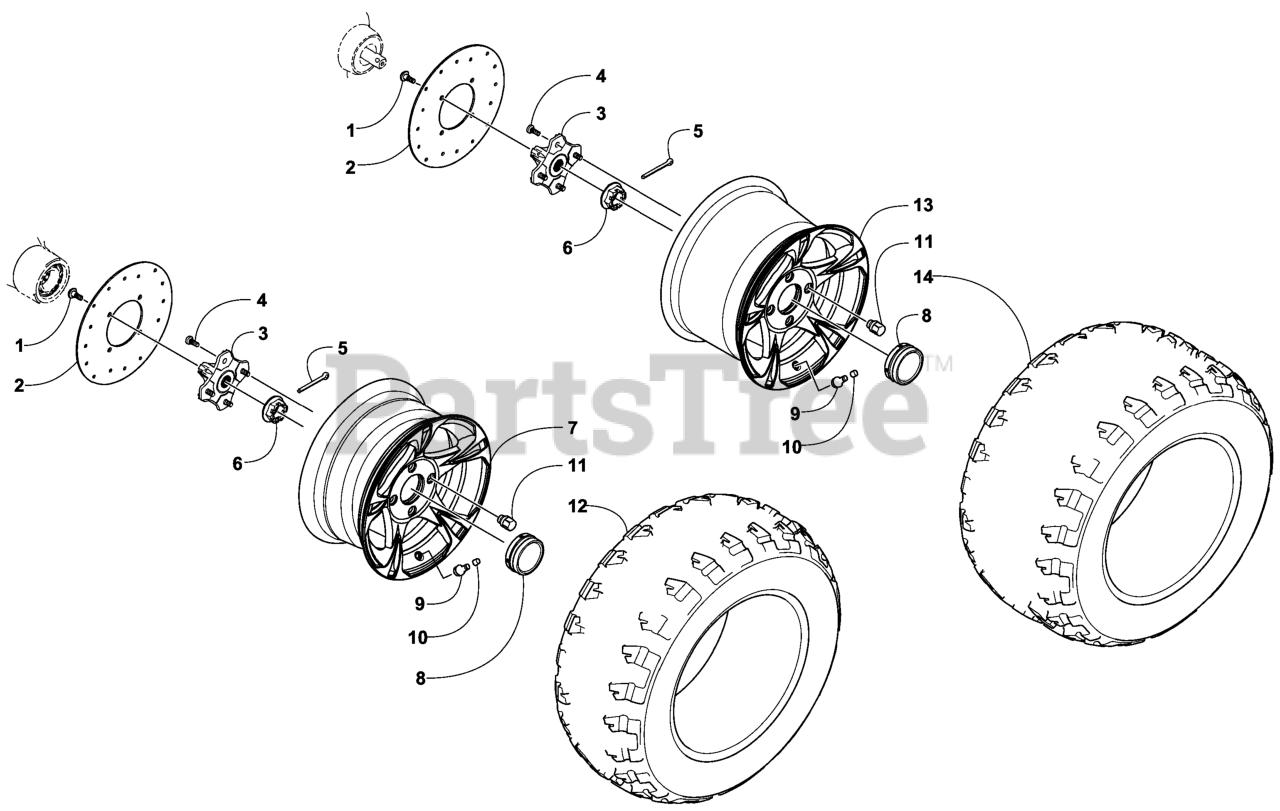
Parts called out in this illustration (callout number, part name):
1	SCREW-SHOULDER
2	KIT-BRAKE DISC
2	KIT-DISC, BRAKE
3	HUB ASM
4	STUD-WHEEL
5	PIN-COTTER
6	NUT-HHF, CASTLE
7	WHEEL-FRONT
8	CAP-WHEEL
9	VALVE STEM
10	CAP-VALVE STEM
11	NUT-LUG
12	TIRE (26 X 9 R14)
13	WHEEL-REAR
14	TIRE (26 X 11 R14)
